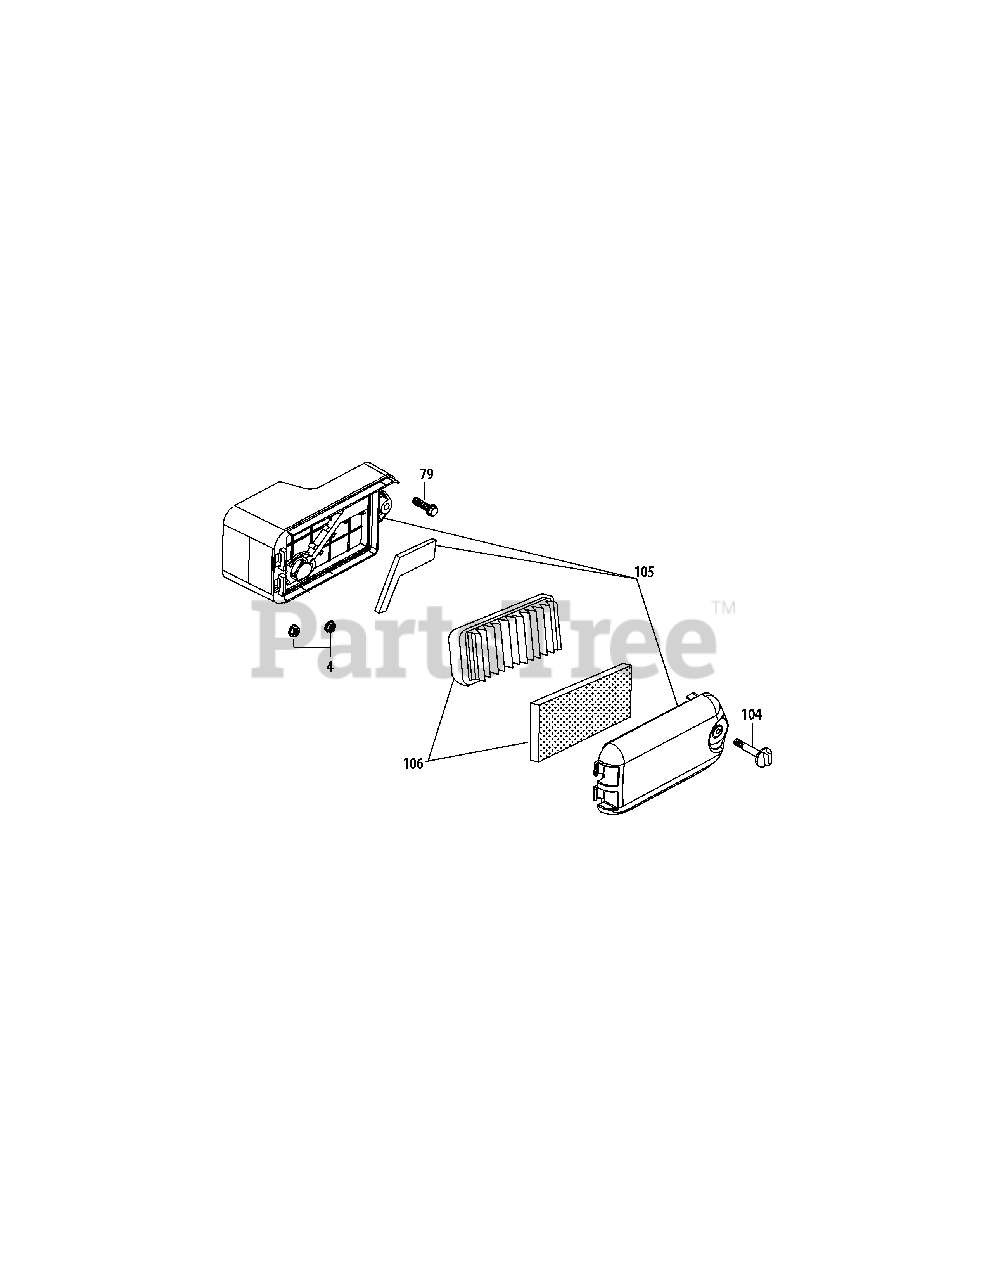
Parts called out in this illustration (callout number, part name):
4	Nut M6 X 10 Mm
79	Bolt M6×35
104	Air Filter Cover Thumb Screw
105	Air Cleaner Housing Assy
106	Air Cleaner Kit
